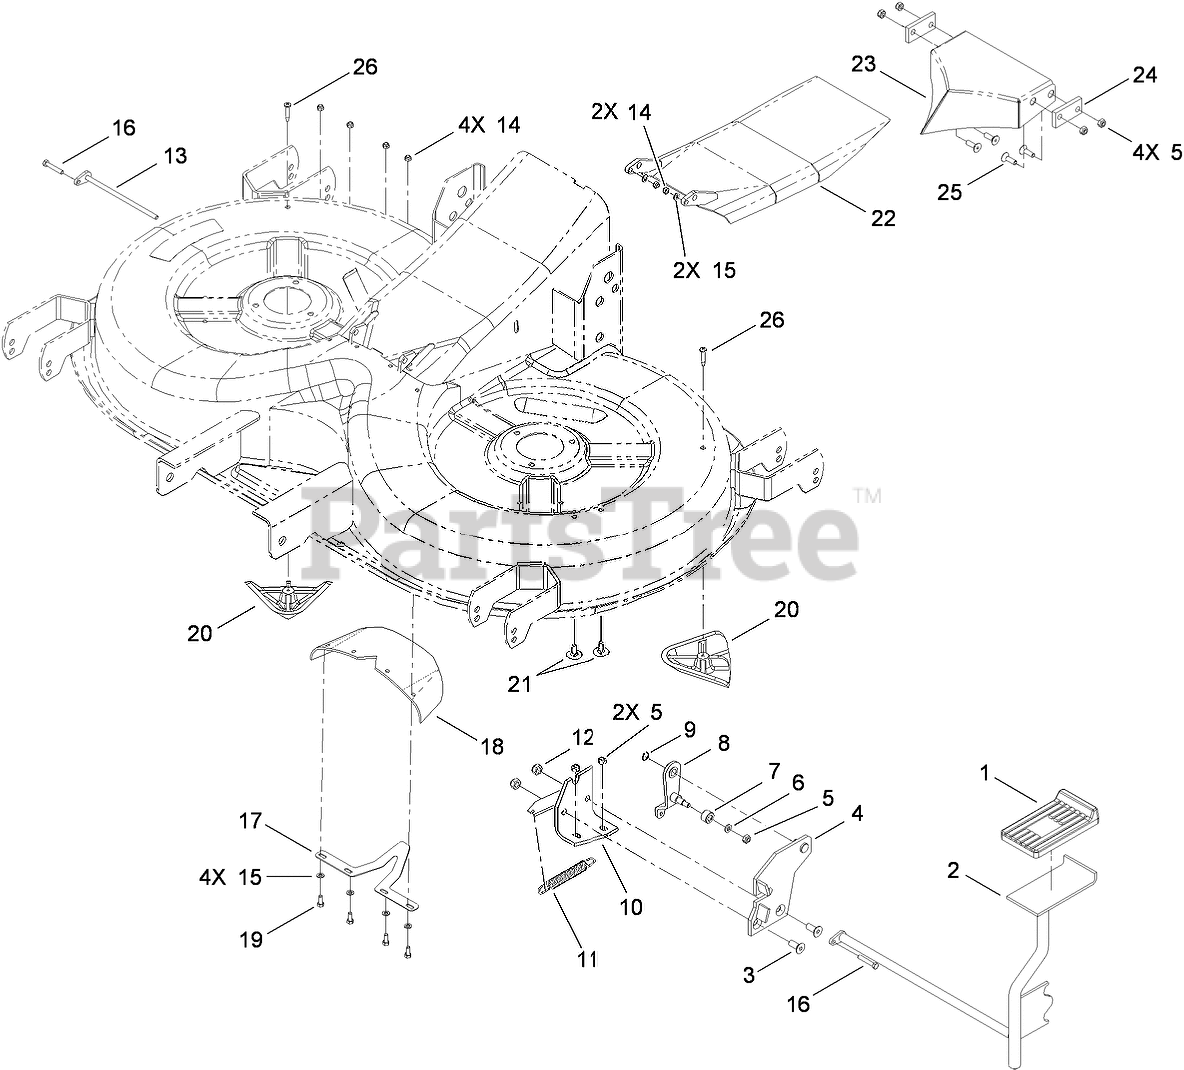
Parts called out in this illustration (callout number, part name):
1	Cover-Lever, FOOT
2	Lever-Foot
3	SCREW-HSFH
4	Plate-Stop
5	NUT-LOCK
6	WASHER-FLAT
7	Roller
8	Lever-Spring
9	RING-LOCKING
10	Bracket-Mounting
11	Spring
12	NUT
13	Rod-Door, Mulch
14	NUT-LOCK
15	WASHER
18	Gasket-Door, Mulch
19	Screw-HH
20	Kicker
21	SCREW-CARR
22	DOOR-MULCH
23	Baffle-Center
24	PLATE-BAFFLE, CENTER
26	SCREW-TAP, PPH
